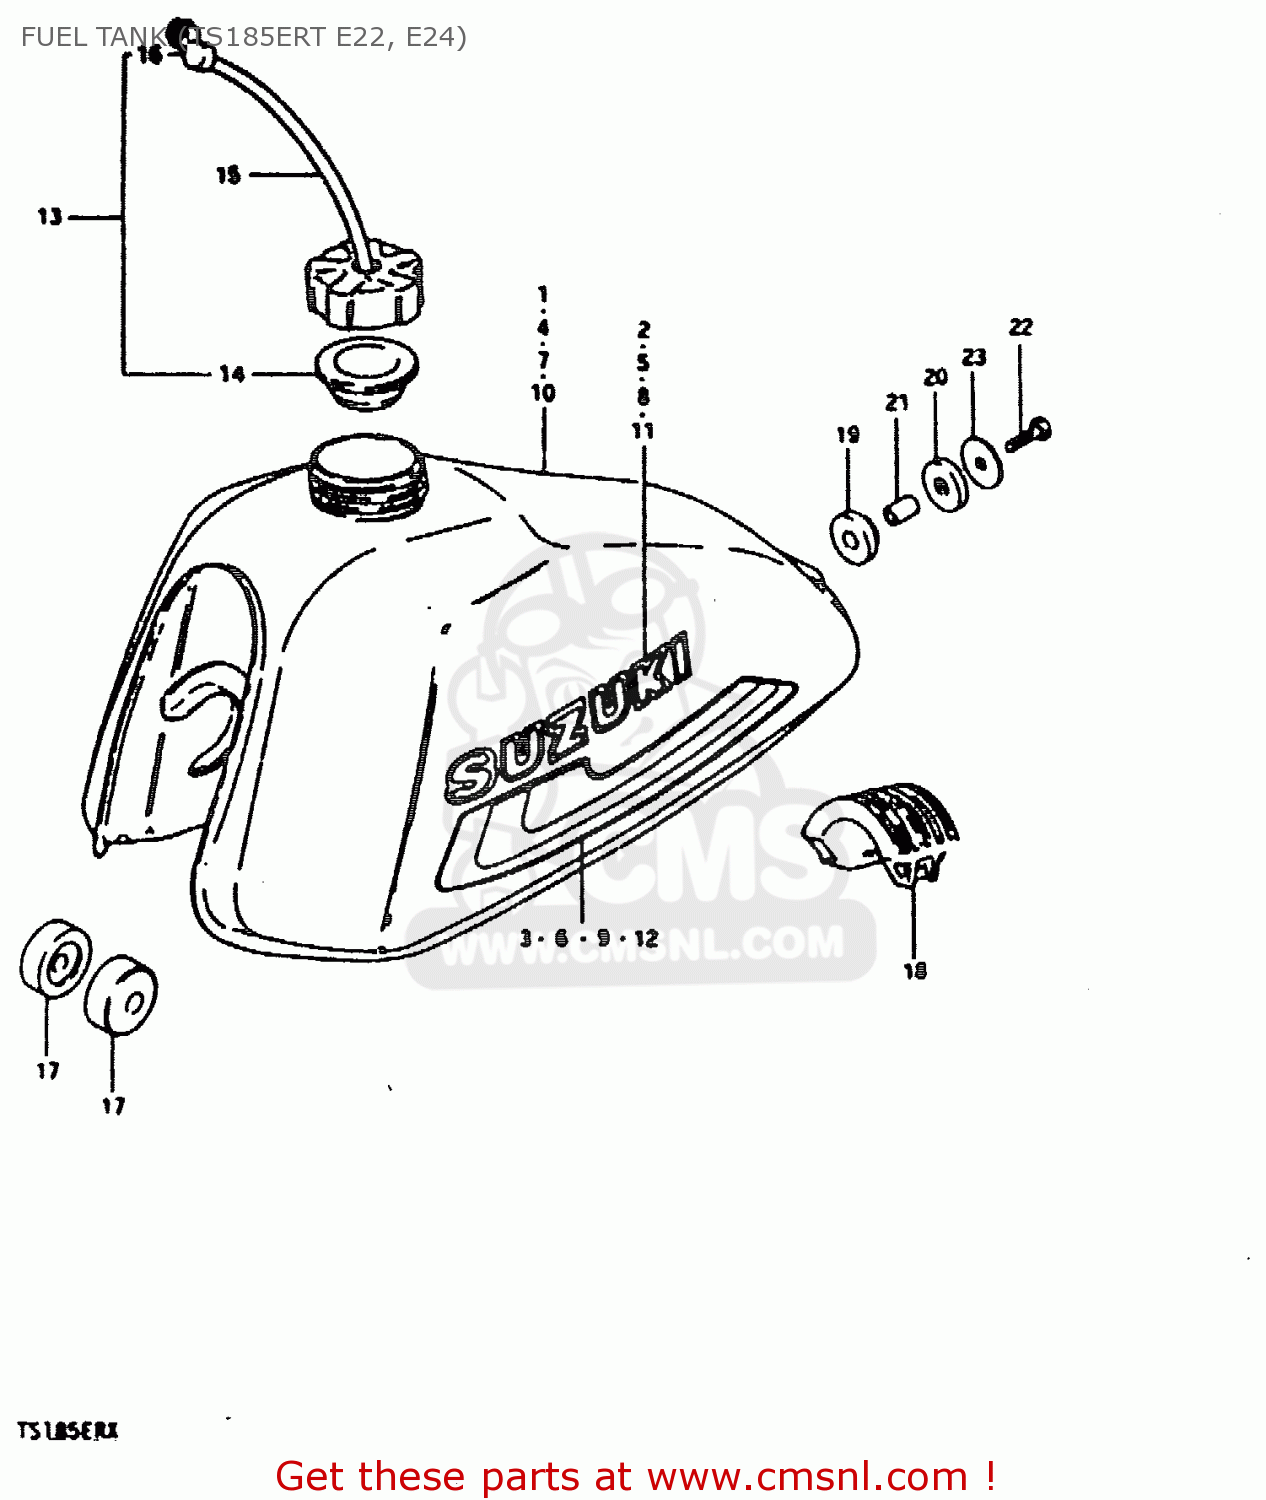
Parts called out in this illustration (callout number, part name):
1	TANK, FUEL (BLACK)
2	EMBLEM,FUEL TANK(WHITE)
3	TAPE SET
4	TANK, FUEL (YELLOW)
5	EMBLEM
6	TAPE SET
7	TANK, FUEL (RED)
8	EMBLEM,FUEL TANK(WHITE)
9	TAPE SET
10	TANK, FUEL (WHITE)
11	EMBLEM
12	TAPE SET
13	CAP SET,FUEL TANK
14	GASKET,FUEL TANK CAP (NAS)
15	HOSE
16	CLAMP,FUEL TANK BREATHER HOSE
17	CUSHION
18	CUSHION,FUEL TANK
19	CUSHION
20	CUSHION
21	SPACER(8.5X12X19)
22	BOLT (8X30)
23	WASHER (8.5X29X1.6)
